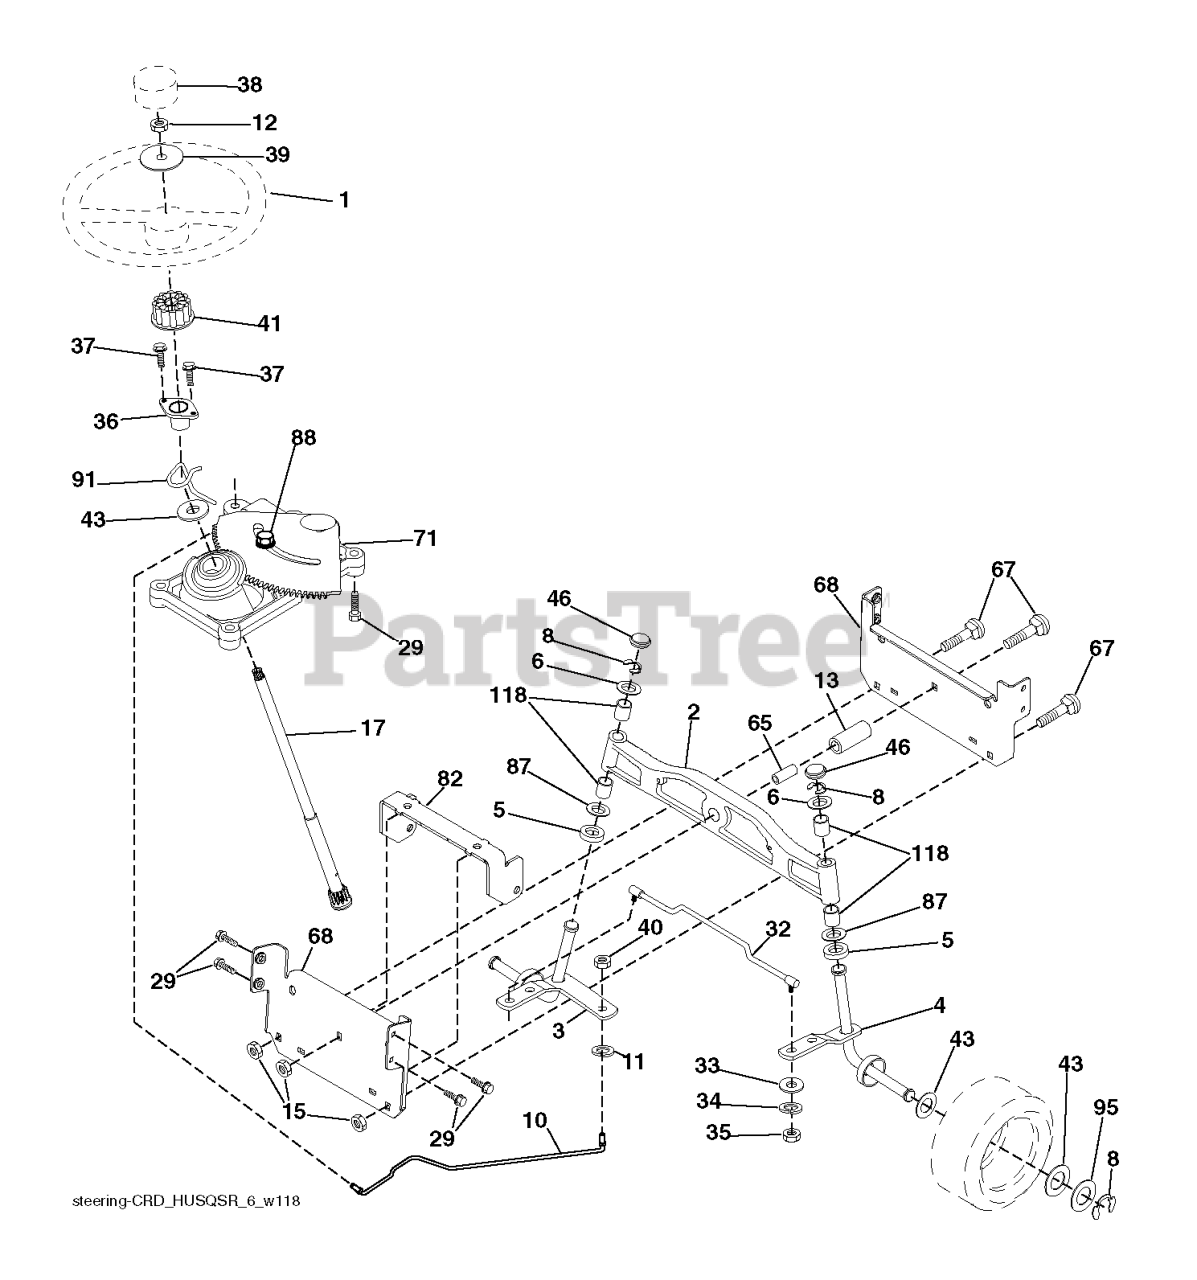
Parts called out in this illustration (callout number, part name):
1	RP WHEEL.STEER.HUSQ.PREM.OVMLD
2	AXLE ASSY FRONT
3	SPINDLE.ASM.LH.15"TIRES
4	SPINDLE.ASM.RH.15"TIRES
5	THRUST WASHER
10	DRAGLINK.15".TIRES.2001
11	WASHER, LOCK 3/8
12	NUT.HEX.1/2-20
13	TUBE, PIVOT AXLE
15	NUT
17	SHAFT ASM STRG
29	SCREW, 3/8-16X3/4
33	WASHER M
34	WASHER.LOCK.HVY.HLCL.SPR.5/16
35	NUT, CROWNLOCK
36	BUSHING, STRG. BLK
37	SCREW.TT.#10-32X.5.3/8.FLANGE
38	RP INSERT.CAP.WHL.STRG.HUSQ.
39	WASHER 9/16"ID, 2 3/8"OD
40	NUT CROWNLOCK 3/8-24
41	ADAPTER, WHEEL STNG..
46	CAP.SPINDLE.BLACK
65	SPACER.BRACE.AXLE
67	BOLT CARRIAGE
68	BRACE.AXLE.15"TIRES
71	STEERING ASM
82	BRACKET.SUSP.CHASSIS.FRONT.15
87	WASHER, FLAT .781 X 1 1/2"
88	BOLT, SHOULDER 7/16-20
91	CLIP.STEERING
95	WASHER.HARDENED
118	BUSHING, AXLE CAST
